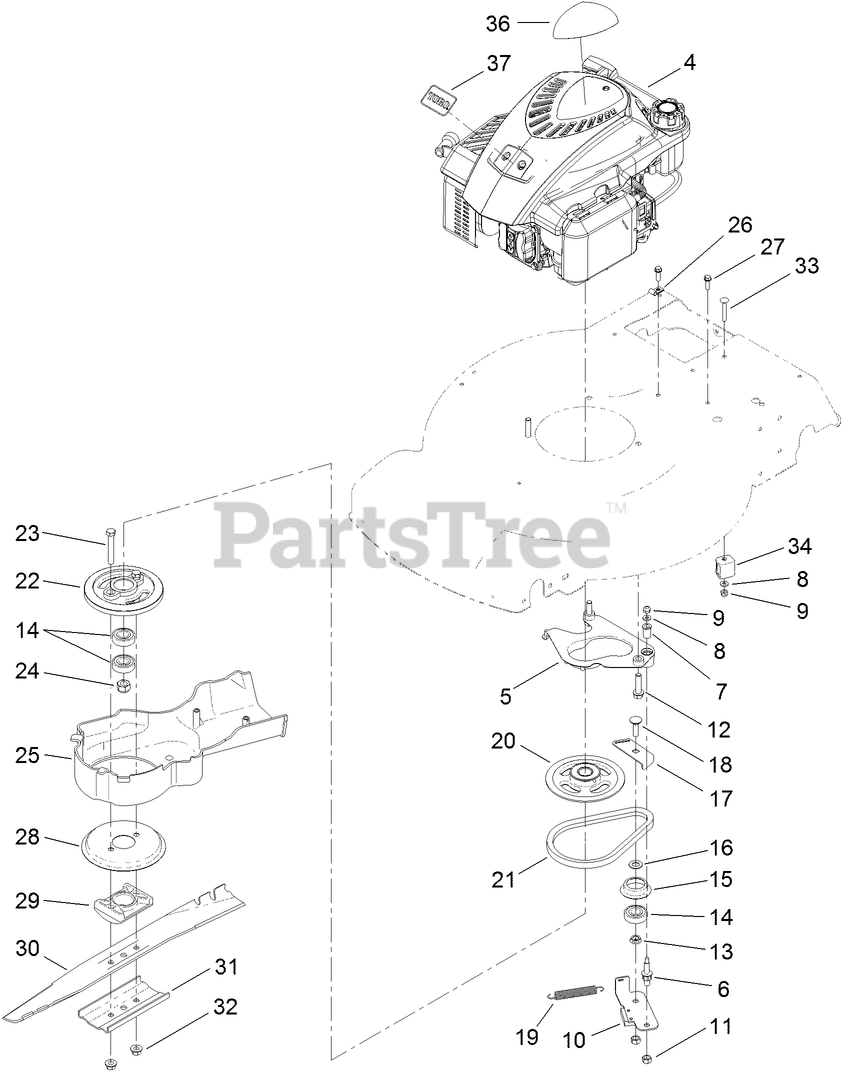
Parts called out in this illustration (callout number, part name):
5	PLATE-ANCHOR
6	BOLT-SHOULDER
7	BUSHING
8	WASHER-FLAT
9	NUT-LOCK, NI
11	LOCKNUT
12	SCREW-HWH
13	SPACER-BEARING
15	RETAINER-BELT
16	SPACER
17	PLATE-GUIDE
18	BOLT-CARR
19	SPRING-TENSION, BRAKE
20	PULLEY
21	BELT
23	SCREW-HH
24	NUT-HEX
26	CLIP-CLOSED, INSULATED
27	SCREW-HWH
28	DISC
29	SUPPORT-BLADE
31	SUPPORT-BLADE
32	NUT-LOCK
33	SCREW-CARR
34	ANCHOR-CABLE
36	DECAL-SHROUD
